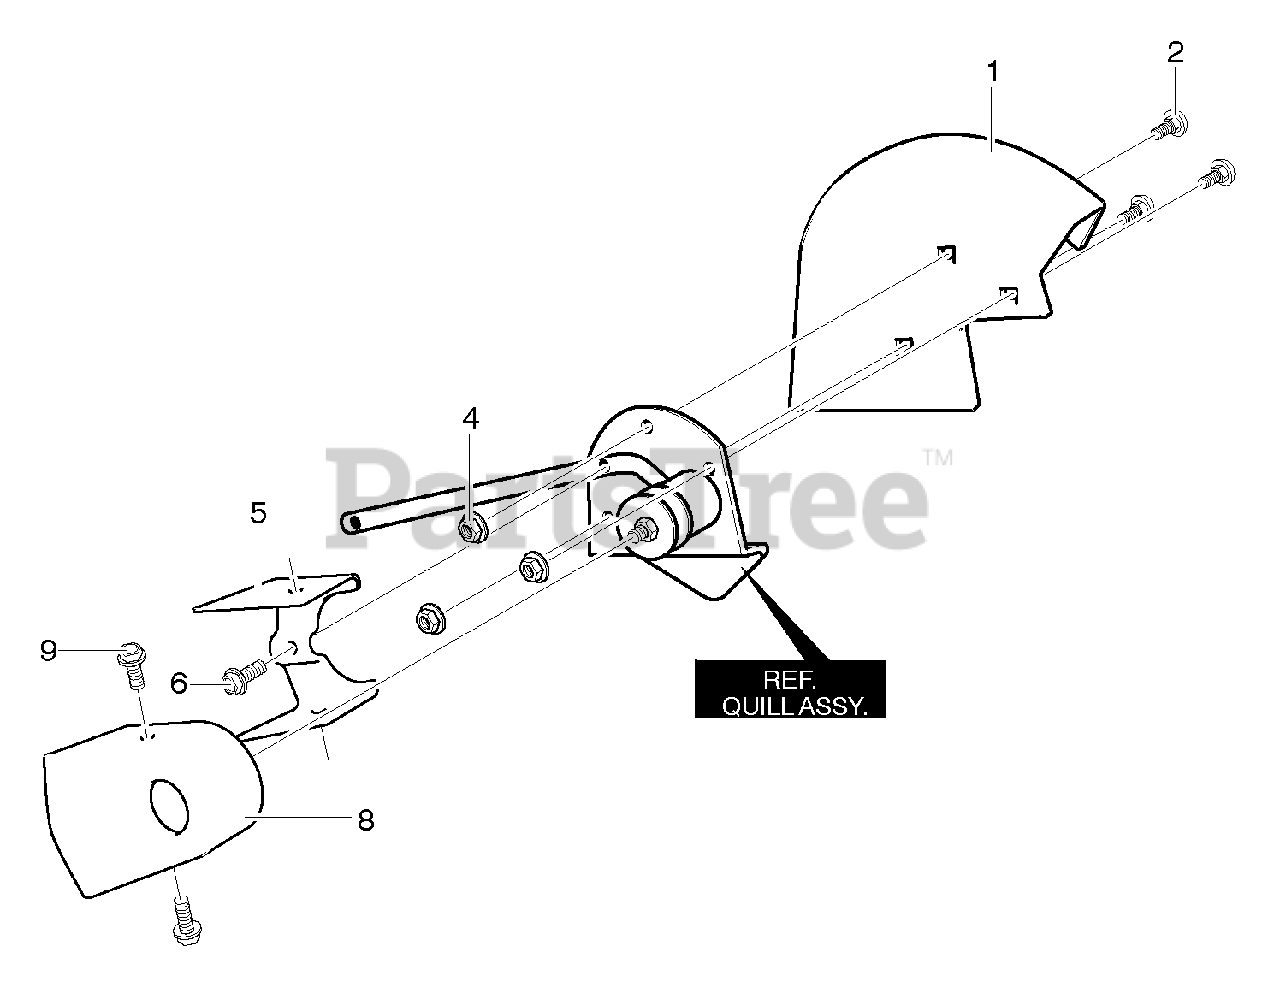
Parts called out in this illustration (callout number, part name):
1	Blade Guard
2	Bolt, Carriage
4	Nut, 5/16-18
5	Guide, Belt Front
6	Screw, 1/4-20x.50
8	Cover, Quill Pulley
9	Screw, 10-16x.50
